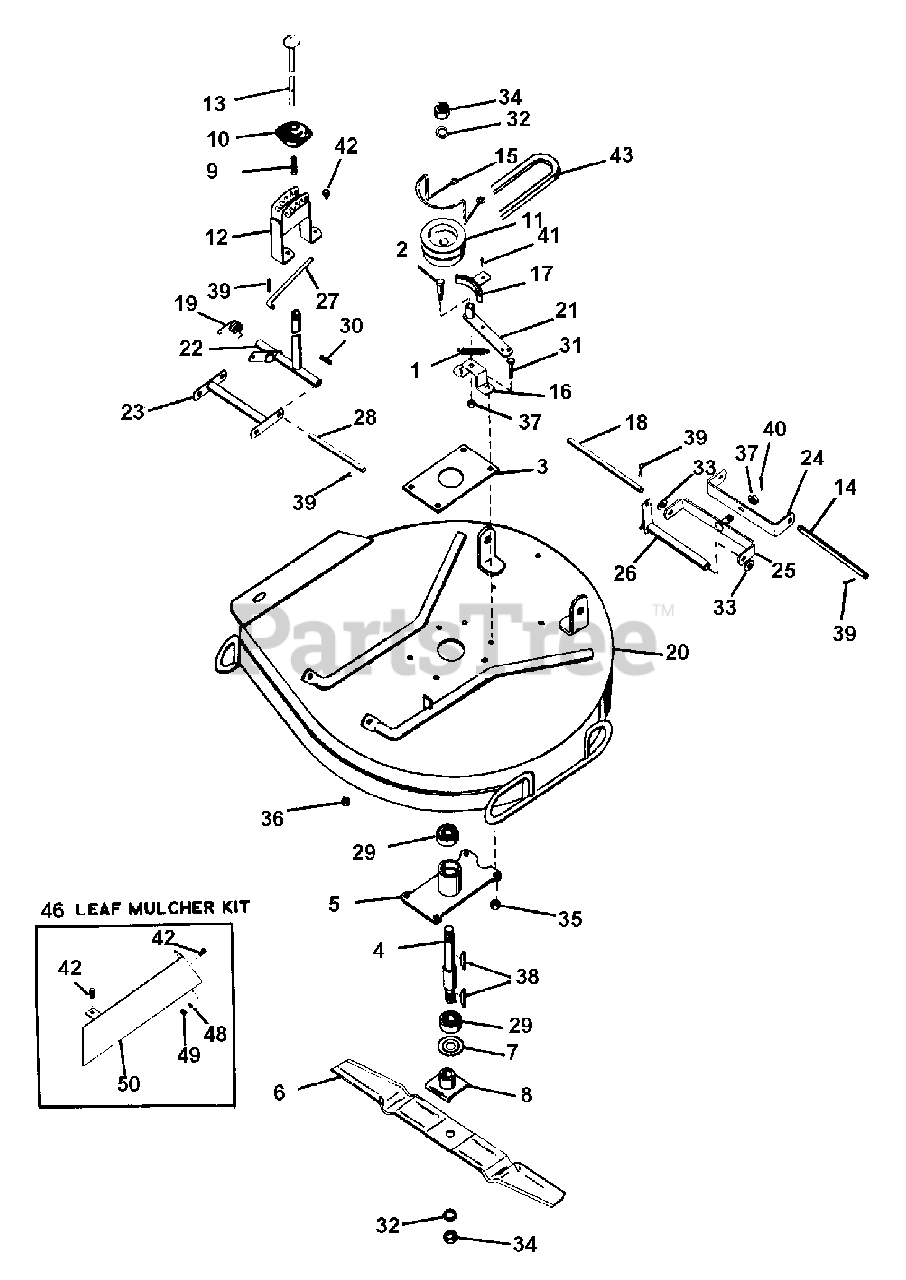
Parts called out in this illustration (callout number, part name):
1	SPRING
2	SHOULDER BOLT .50 X 1.75
4	MOWER SPINDLE
5	SPINDLE HOUSING
6	BLADE, MOWER
7	BEARING SLINGER
8	BLADE RETAINER
9	SPRING
10	SHIFT BALL
11	MOWER SHEAVE
12	MOWER HGHT QUAD
13	HGHT CNTL PLNGR
14	REAR BRACKET PIN
15	MOWER BELT FINGER
16	BLADE BRAKE SUPPORT
17	BLADE BRAKE
18	HANGER PIN
19	FLOAT LIMIT SPRING
20	MOWER PAN
21	BLADE BRAKE ARM
22	HGHT CNTL ARM
23	FLOATING LINK
26	REAR RAISING BRACKET
27	HGHT LINK ROD
28	ADAPTER PIN
29	BRG-BALL .751X1.78X.61
30	PIN-ROLL .250X1.25
31	BLT-HEX .38-16X1.00 PL
32	WSHR-LK .750X.188 MED PL
33	WSHR-FL-STL .531X1.062X.095 PL
34	NUT-JAM .625-11
35	NUT-LK-CTR .375-16 GR A PL
36	NUT-LK .312-18 GR A PL
37	NUT-JAM-SL .625-18
38	KEY-WDRF .188X.75X.313 SAE 9
39	PIN-COTR .12X1.0 PL
40	PIN-COTR .09X.75 PL
41	RVT .25X.50 RH ST
42	BLT-SERHFWH .31-18X.50 PL
43	BELT,5L RAW LAMINATED
46	Leaf Mulcher Kit(Inc. 47,48,49,50)
47	BLT-SERHFWH .31-18X.50 PL
48	WSHR-LK .312X.097 PL HVY
49	NUT-JAM .375-16 PL
50	LEAF MULCHER
